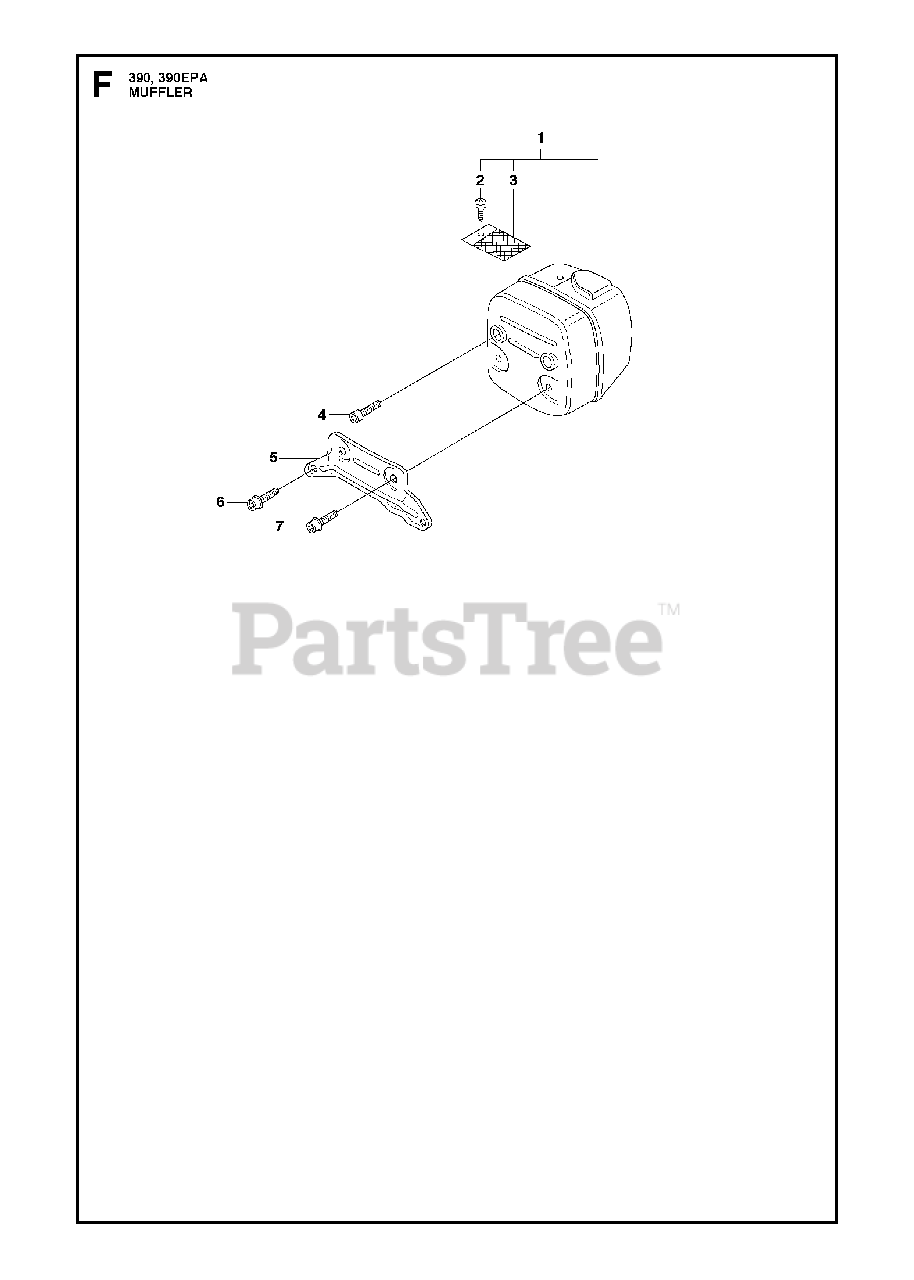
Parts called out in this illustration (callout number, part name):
1	RP MUFFLER ASSY
1	MUFFLER ASSY
2	SCREW
3	SCREEN
4	SCREW MC6S 6X20
